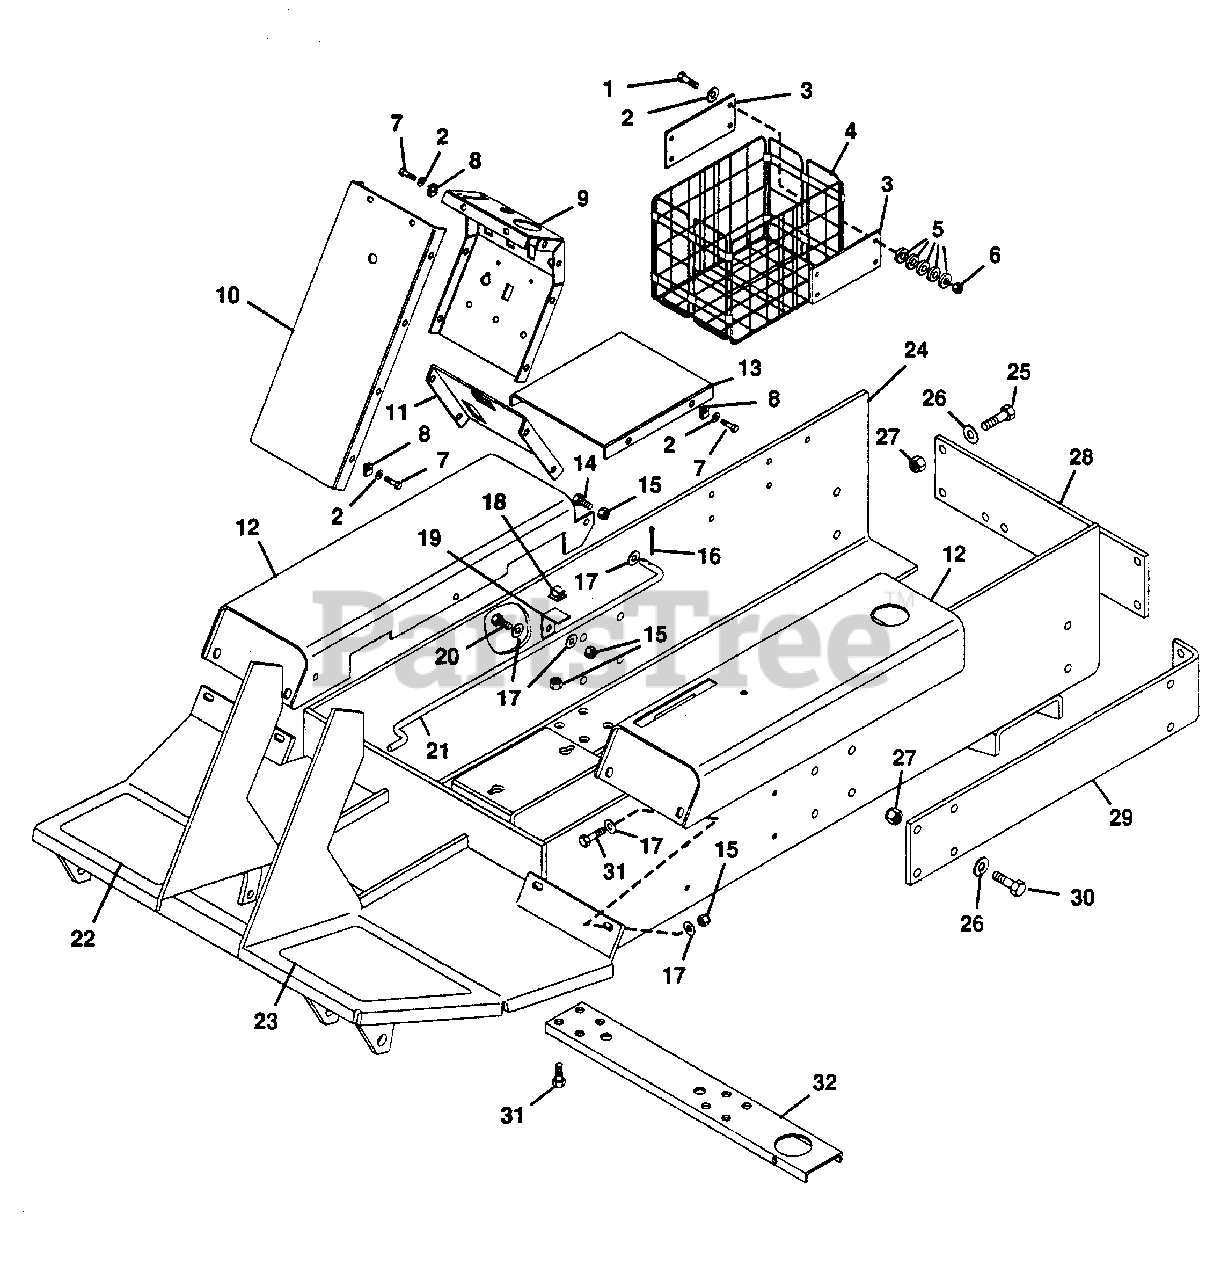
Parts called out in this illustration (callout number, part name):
1	Bolt, Hex 1/4-20x1.50
2	Washer, Flat .281x.625x.065
3	Strap, Basket
4	Basket
5	Washer, Friction
6	Nut, Lock 1/4-20
7	Screw, Machine 1/4-20 PHD
8	Nut, Retainer
9	Panel, Instrument Silk Screen
10	Panel, Front Silk Screen
11	Panel, Brake Lock Silk Screen
12	Fender, R.H. Silk Screen
12	Fender, L.H. Silk Screen
13	Panel, Access Silk Screen
14	Bolt, Hex 3/8-16x.75
15	Nut, Lock 3/8-16
16	Pin, Cotter .094x.75
17	Washer, Flat .406x.812x.065
18	Clip, Wire
19	Bracket, Stay Rod
20	Bolt, Hex 3/8-16x1.00
21	Rod, Stay
22	Cover, R.H. Foot
23	Cover, L.H. Foot
24	Weldment, Frame
25	Bolt, Hex 1/2-13x1.50
26	Washer, Flat .531x1.062x.095
27	Nut, Lock 1/2-13
28	Plate, Bumper
29	Bumper
30	Bolt, Hex 1/2-13x1.25
31	Bolt, Hex 3/8-16x.875
32	Brace, Frame
